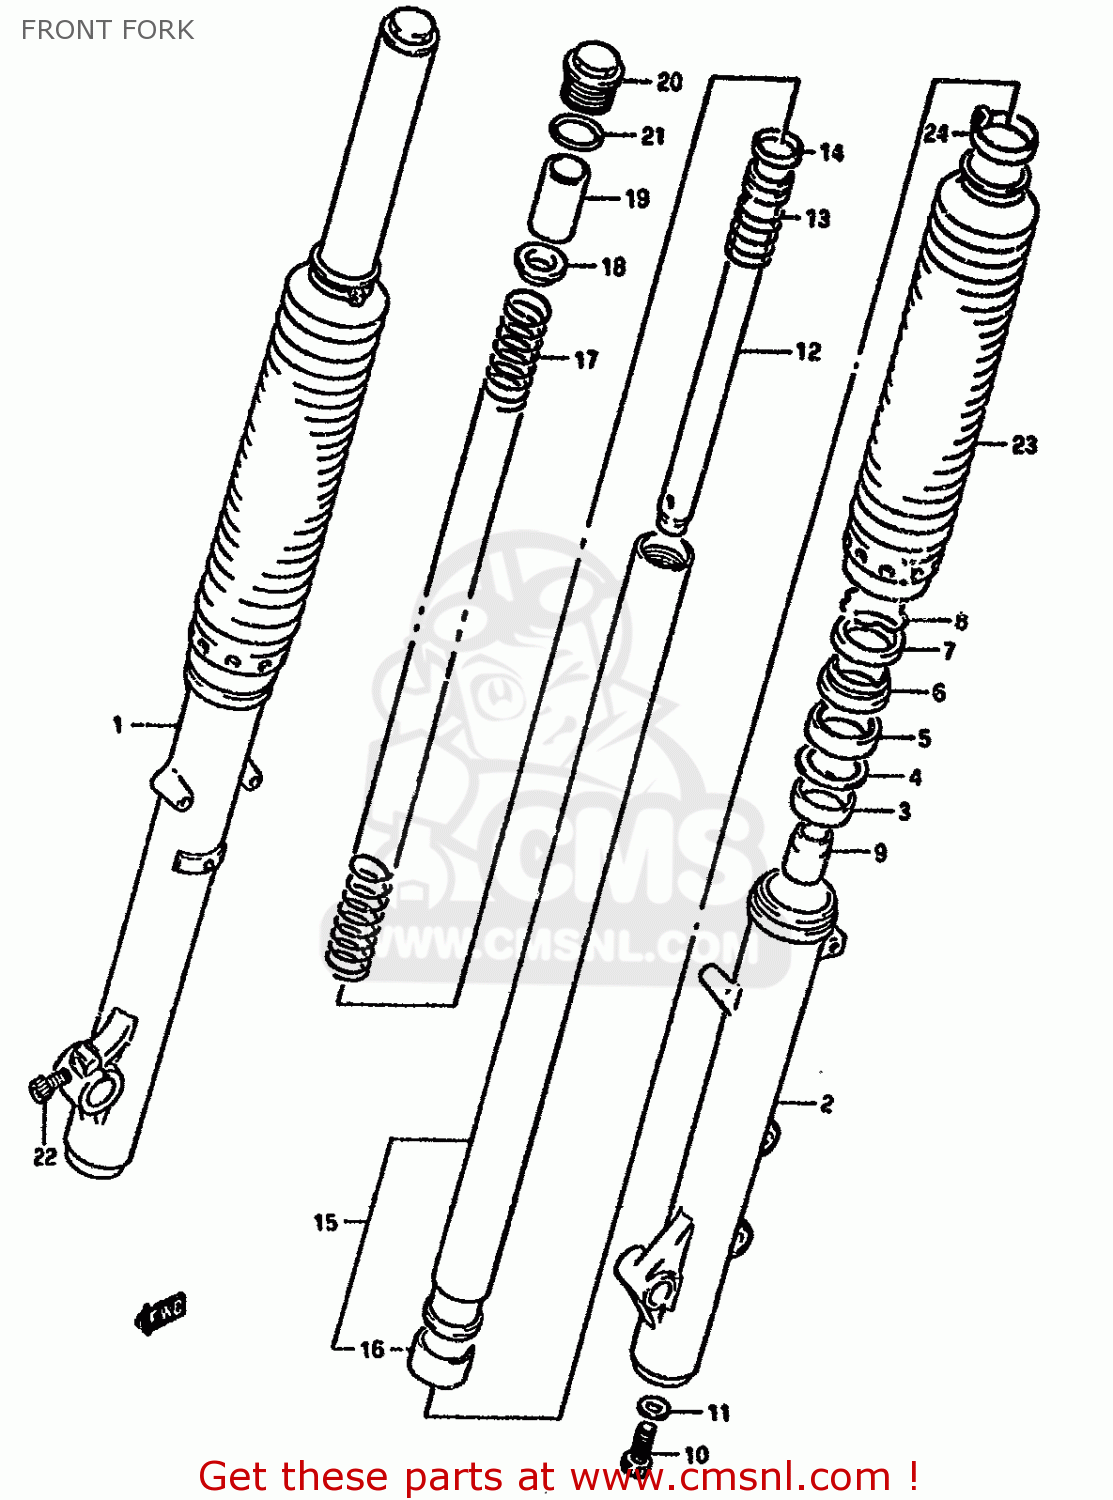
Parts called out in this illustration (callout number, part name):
1	TUBE,OUTER,R
2	TUBE,OUTER,L
3	METAL,SLIDE
4	WASHER,FORK OIL SEAL
5	SEAL,OIL
6	SEAL,DUST
7	WASHER
8	RING,OIL SEAL STOPPER
9	PIECE,OIL LOCK
10	BOLT(14X25)
11	GASKET (NAS)
12	CYLINDER
13	SPRING,REBOUND
14	RING,FR FORK PISTON
15	TUBE,INNER
16	PISTON
17	SPRING,MAIN
18	GUIDE,SPRING
19	SPACER,SPRING
20	CAP,FORK
21	O-RING
22	BOLT,SOCKET HEAD(8X22)
23	BOOT(BLUE)
24	BAND,BOOT
